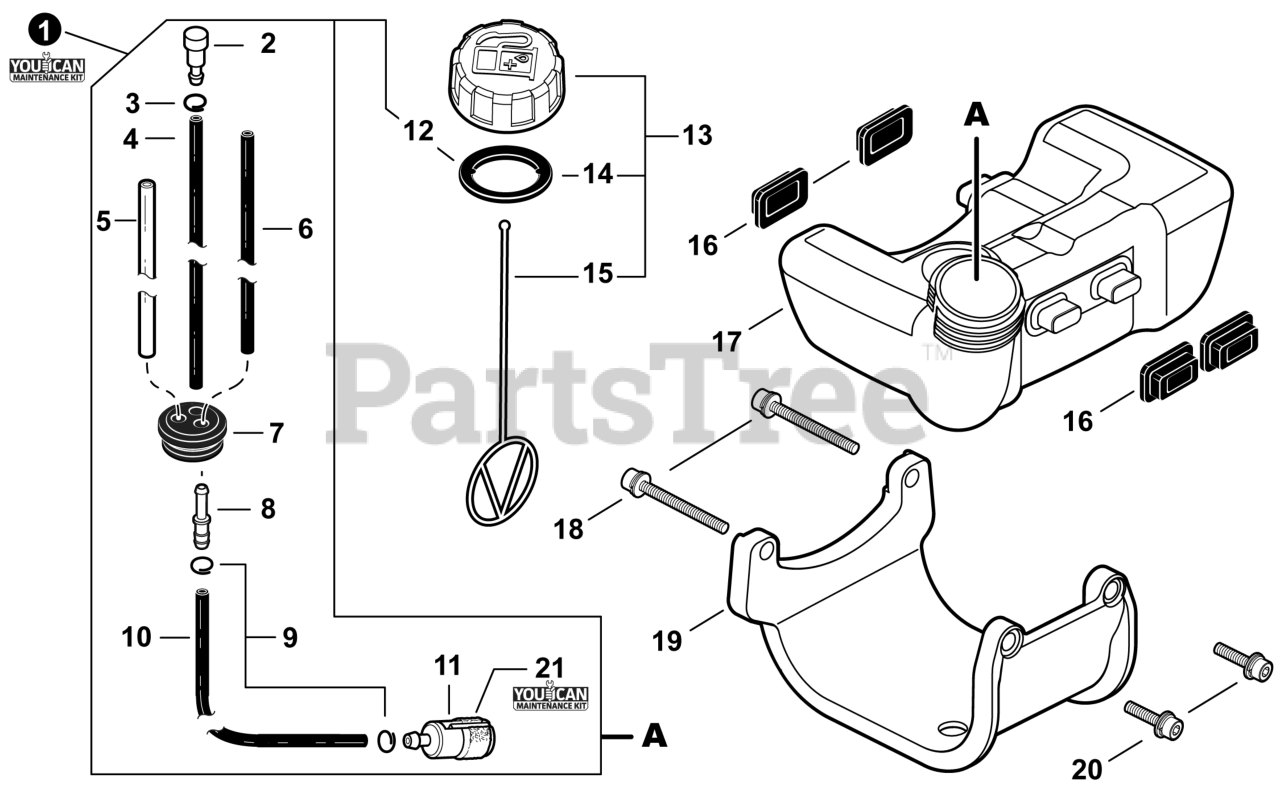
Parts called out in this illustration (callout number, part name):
1	FUEL SYSTEM KIT - YOUCANT
2	VENT ASSY
3	CLIP Ø6.5 MM
4	PIPE, FUEL 3×6×105 BLACK
5	PIPE, FUEL 3×6×85 CLEAR
6	PIPE, FUEL 3×5×74 BLACK
7	GROMMET, FUEL
8	CONNECTOR, PIPE Ø5ר3.5
9	CLIP Ø6
10	PIPE, FUEL 3×5×140 BLACK
11	FILTER, FUEL
12	GASKET, FUEL CAP
13	CAP ASSY, FUEL
14	GASKET, FUEL CAP
15	CONNECTOR, CAP L= 123
16	CUSHION, FUEL TANK
17	TANK, FUEL
18	BOLT 5×40
19	GUARD, FUEL TANK
20	BOLT 5×18
21	TUNE-UP KIT - YOUCANT
